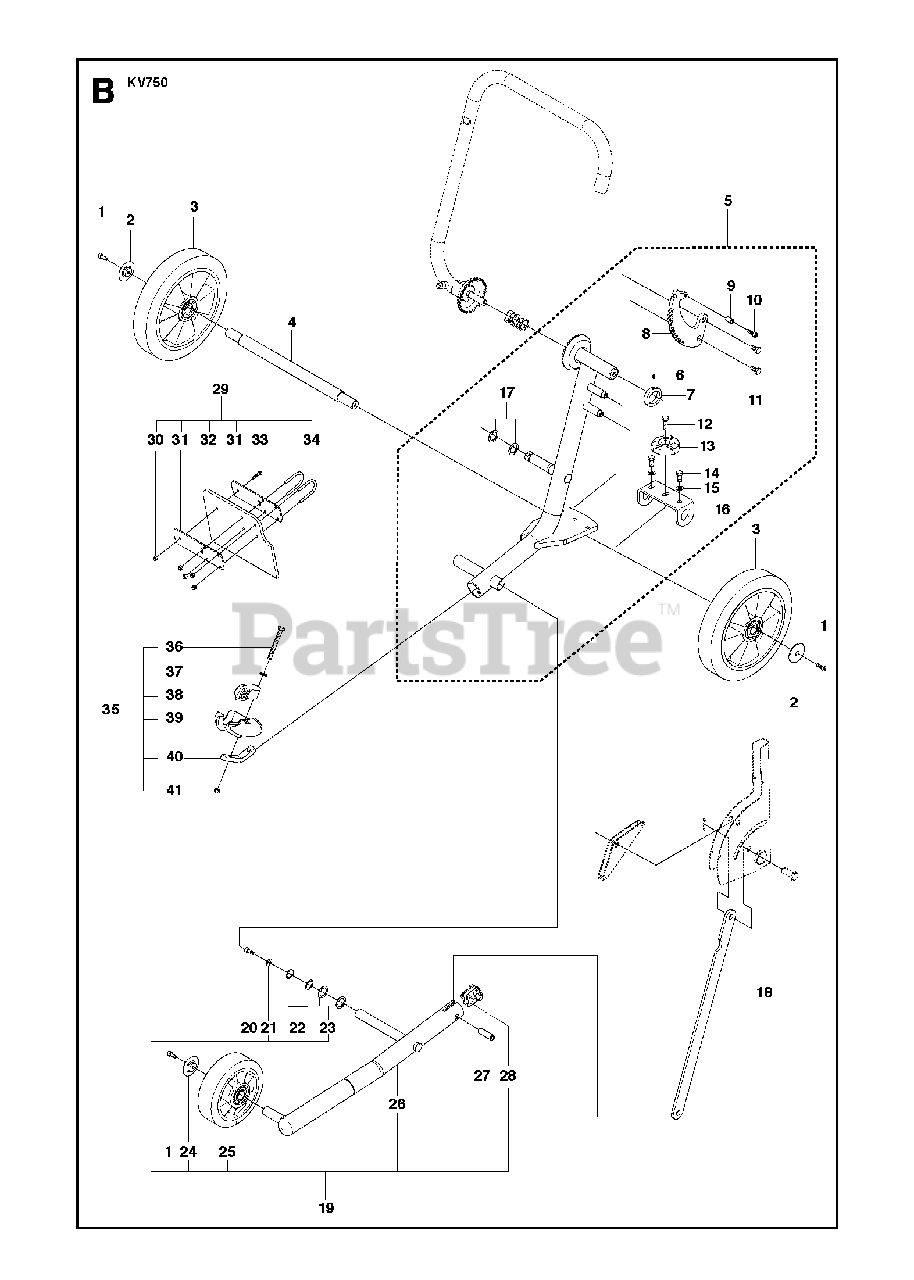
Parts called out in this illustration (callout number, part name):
10	SCREW IHSCM
11	SCREW EHHM
13	TURNING KNOB
19	FRAMEIncl. 20 - 28
20	SCREW EHHM
30	HEXAGON LOCKING NUT
37	WASHER
38	TURNING KNOB
41	HEXAGON NUT
